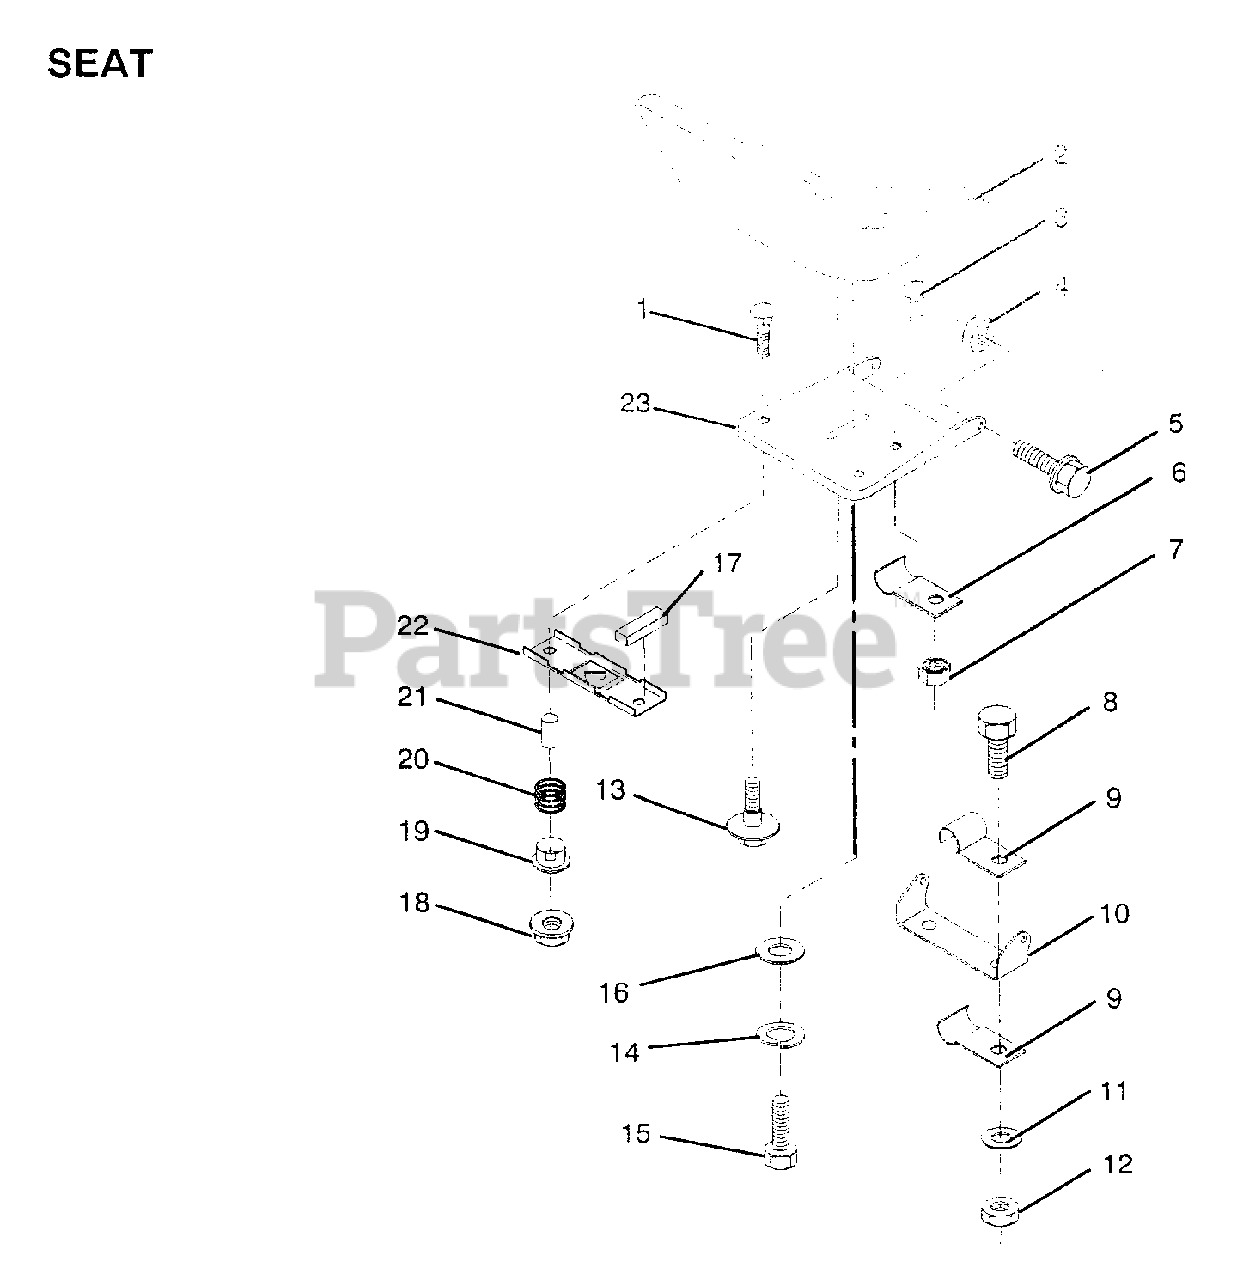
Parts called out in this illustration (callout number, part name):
1	BOLT
7	"NUT,KEPS"
9	"CLIP,INSULATOR"
11	WASHER
13	"BOLT,SHOULDER"
14	LOCKWASHER
15	BOLT
16	WASHER
17	STRIP FORM
19	BUSHING
20	SPRING
21	SPACER SPLIT
22	BRKT SWITCH
